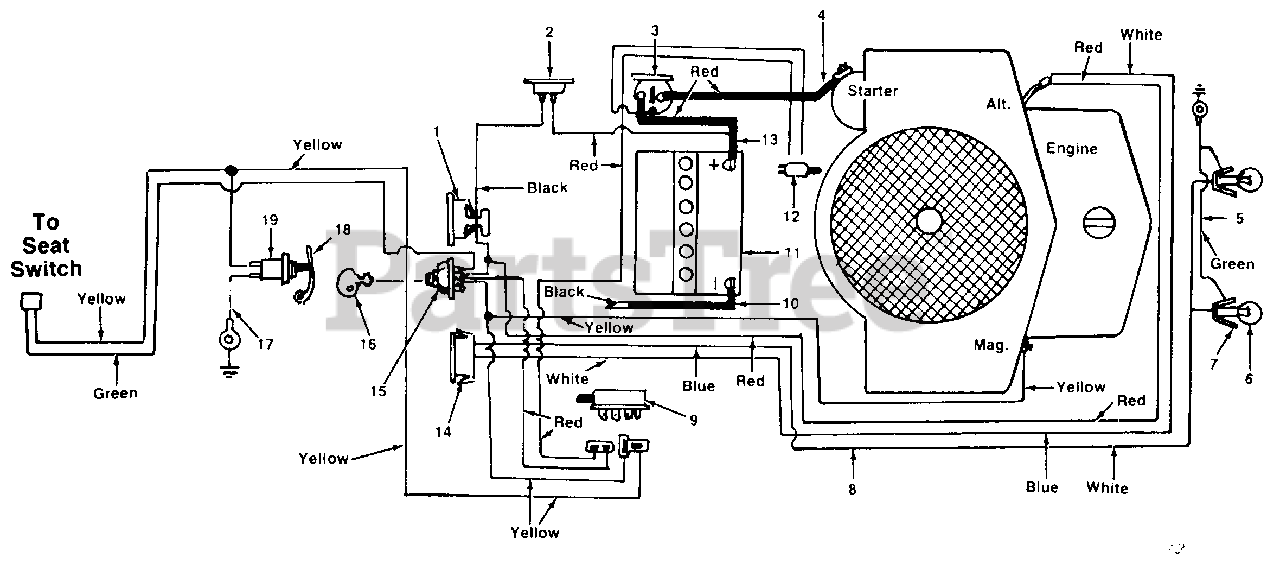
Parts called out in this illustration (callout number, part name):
1	Ammeter
2	Circuit Breaker
3	Solenoid
4	Wire w/Boot
5	Ground Wire
6	Bulb
7	Socket
8	Wire Harness
9	Safety Switch
10	6 Ga. Black Wire
11	Battery 12V
12	Safety Switch
14	Light Switch
15	Ignition Switch
16	Ignition Key
17	Electric Wire
18	Spring Lever
19	Safety Switch
